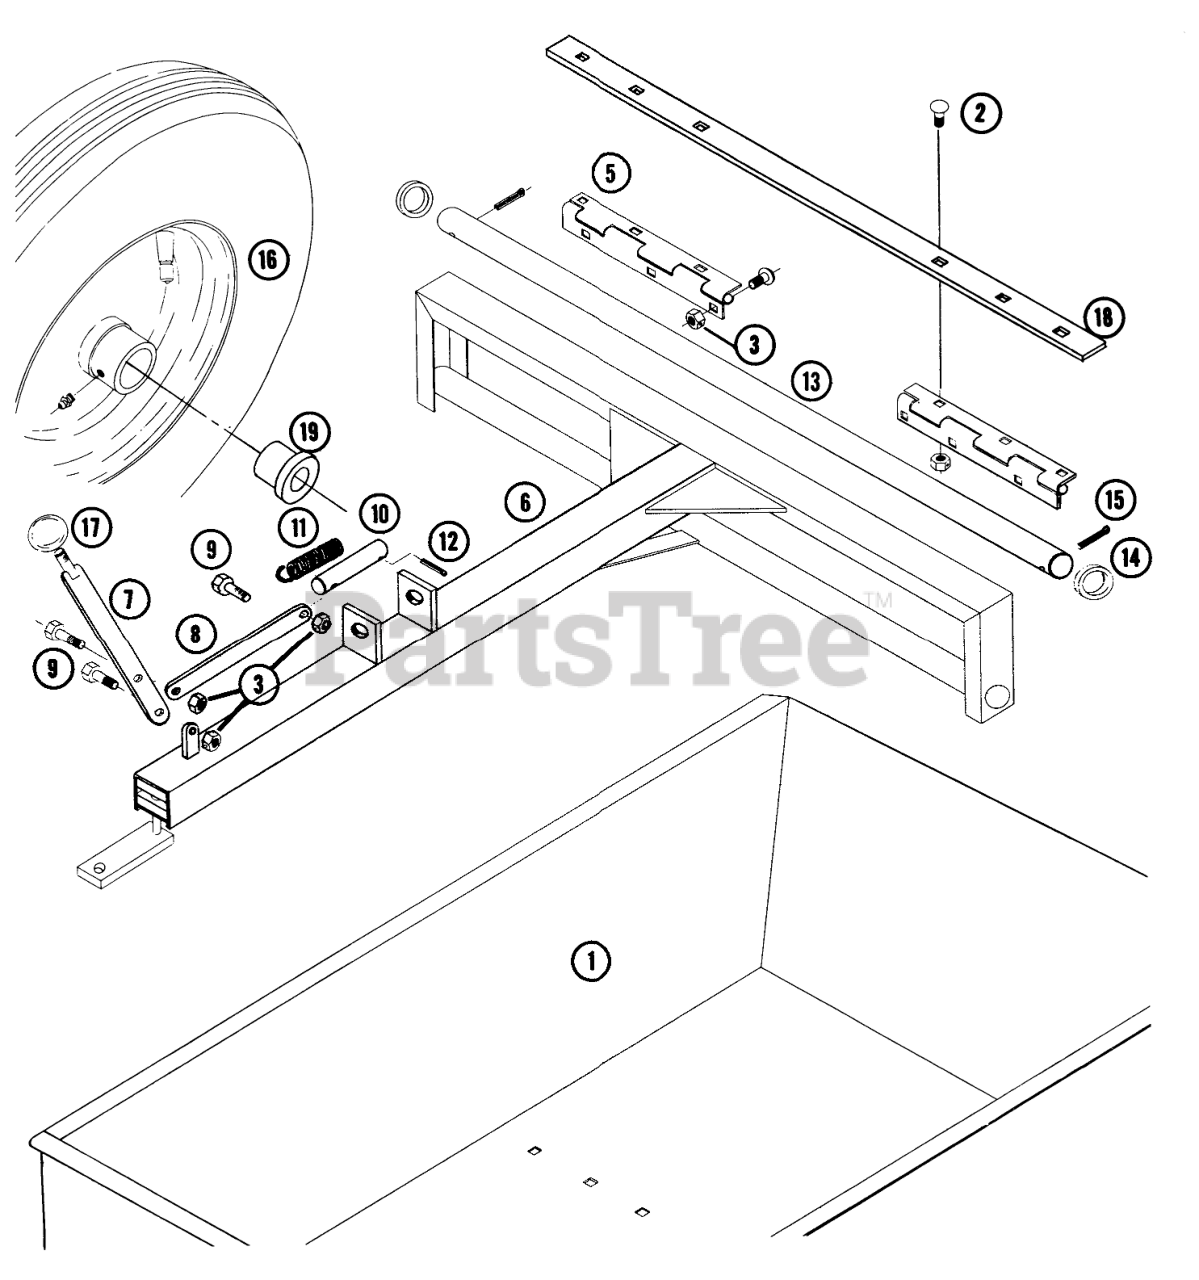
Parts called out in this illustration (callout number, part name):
1	Bed Ass-y. W/A
2	Carriage Bolt 1/4-20 x 5/8
3	Nut-Nylok
4	Trailer Hinge L.H.
5	Trailer Hinge R.H.
6	Frame Ass-y. W/A
7	Handle Ass-y. W/A
8	Latch Bar
9	Bolt-Hex 1/4-20
10	Index Pin
11	SPRING-COMPRESSION
12	Cotter Pin
13	Axle
15	Cotter Pin 3/16 x 1
18	Shim
